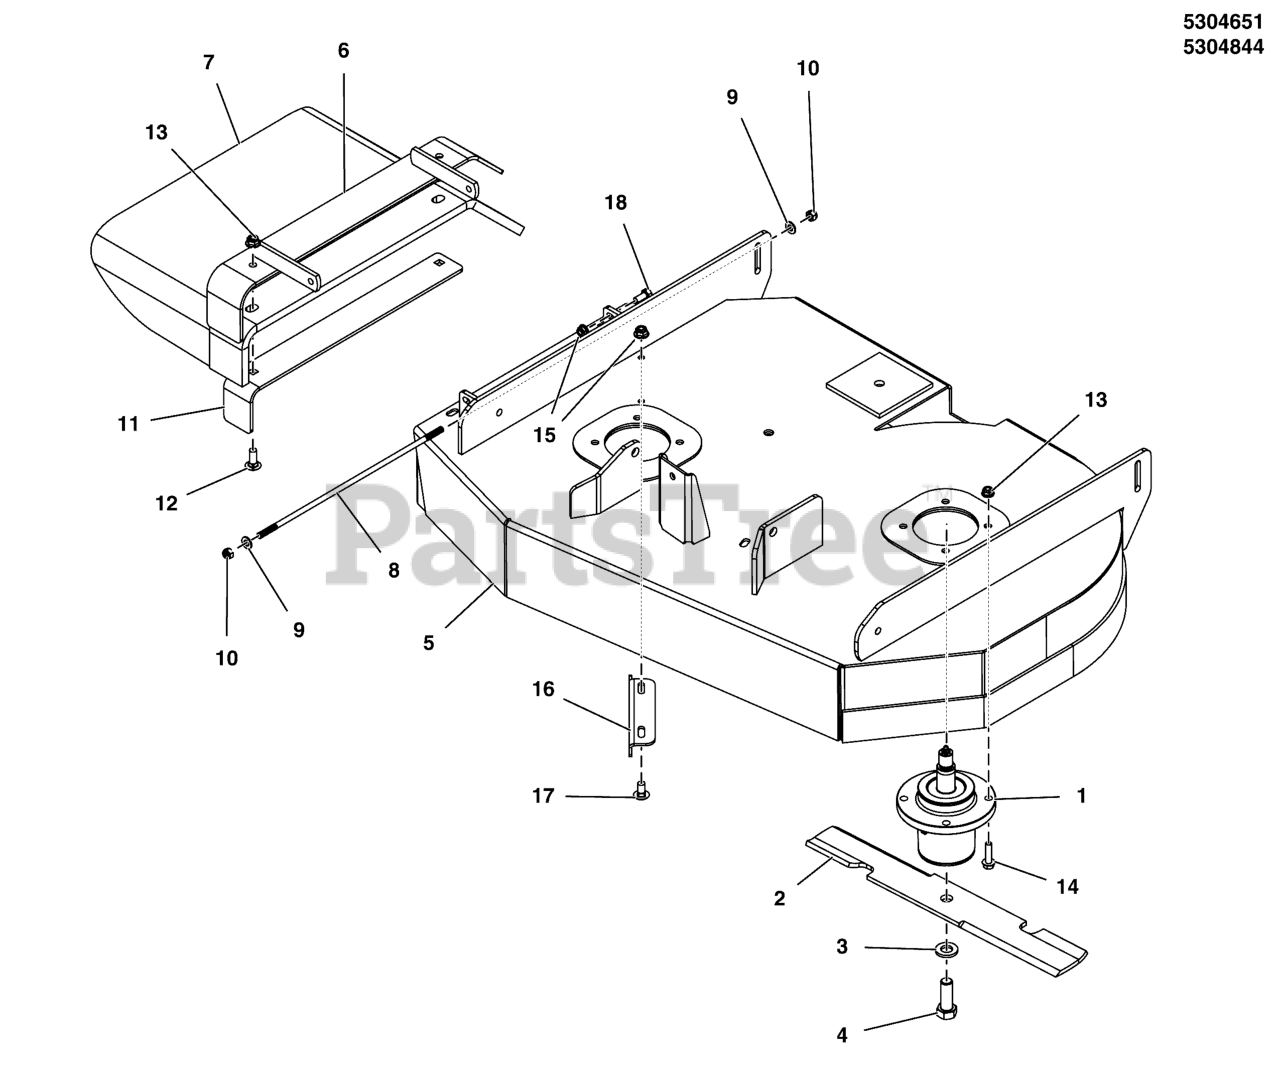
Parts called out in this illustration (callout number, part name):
1	SPINDLE, ASSM, ALUMINUM - 5.25
2	BLADE SET, 36 DECK (2)
3	WASHER, BLADE BOLT, 9/16" F436, CZ
4	BOLT, 5/8-11 X 1-3/4 GD8
5	DECK SHELL W/DECALS, 36, F60Z (5415641B)
6	WELD, MOUNT, DISCHARGE CHUTE - BLK
7	CHUTE, RUBBER DISCHARGE CHUTE (5104441)
8	ROD, 5/16 X 13.75, TBE, CZ
9	WASHER, 5/16" SAE
10	NUT, 5/16-24 HEX NYLON LOCK
11	SUPPORT, DISCHARGE CHUTE - BLK
12	BOLT, 3/8-16 X 1-1/2, CARRIAGE, GD5, CZ
13	NUT, 3/8-16 HEX NYLOCK FLANGE
14	BOLT, 3/8-16 X 1 1/4 FLANGE
15	NUT, 5/16-18 HEX NYLOCK FLANGE
16	PLATE, DEFLECTOR, 36" - BLK
17	BOLT, 5/16-18 X 3/4, CARRIAGE
18	BOLT, 5/16-18 X 3/4 GD5
